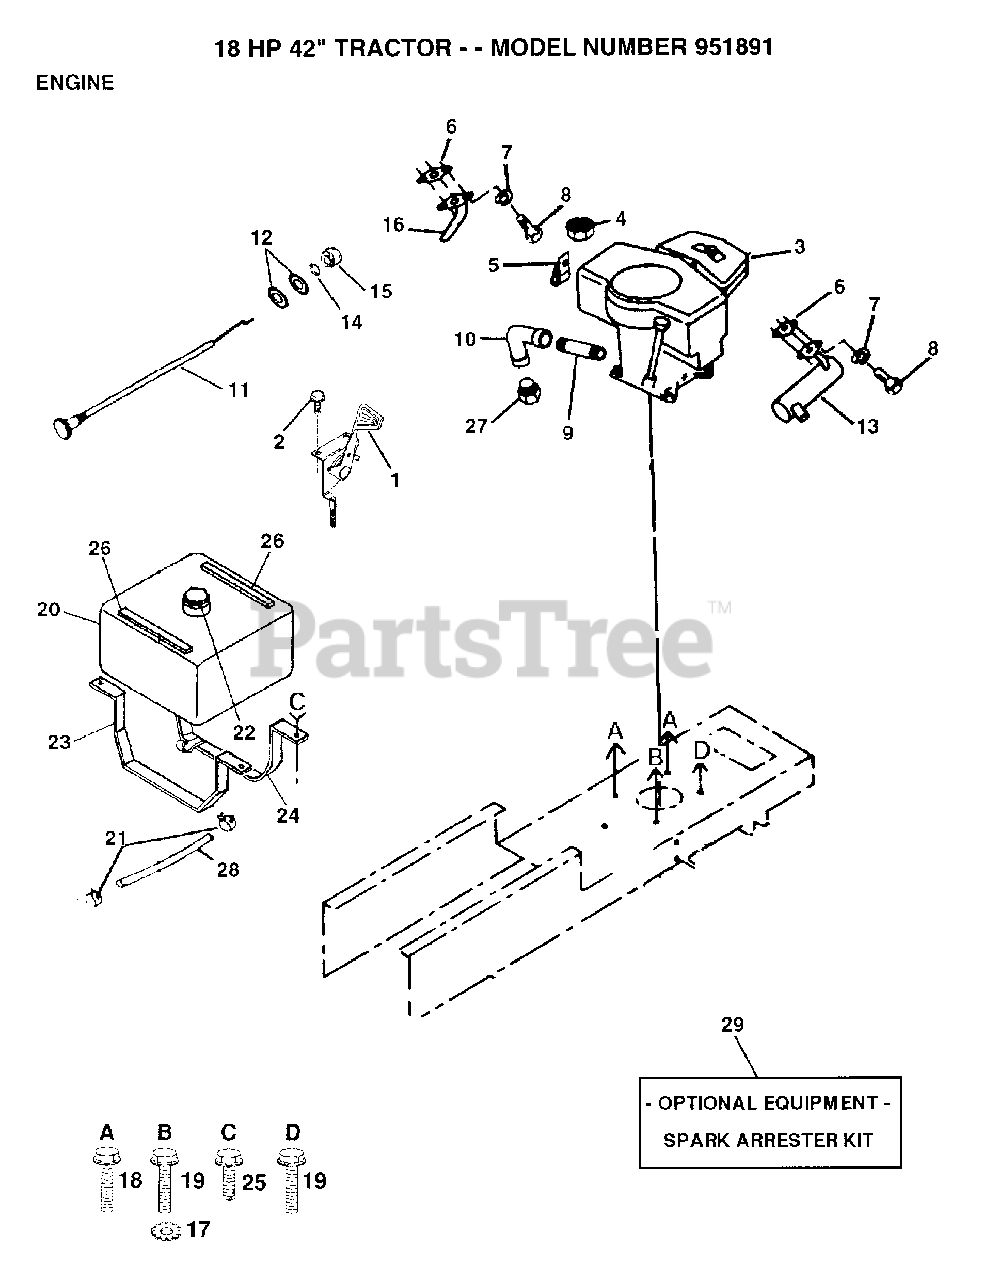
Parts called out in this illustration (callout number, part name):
2	SCREW LT
4	NUT
5	CLIP T
7	LOCKWASHER
9	PIPE NIPPLE LT
10	ELBOW
11	CHOKE CONTROL
12	WASHER
14	LOCKWASHER
16	EXHAUST TUBE T
17	LOCKWASHER
18	SCREW LT
19	SCREW LT
21	HOSE CLAMP
23	"STRAP,TANK"
24	STRAP ASM. F.TANK
25	SCREW LT
26	"STRIP,FORM"
29	SPARK ARREST KIT
